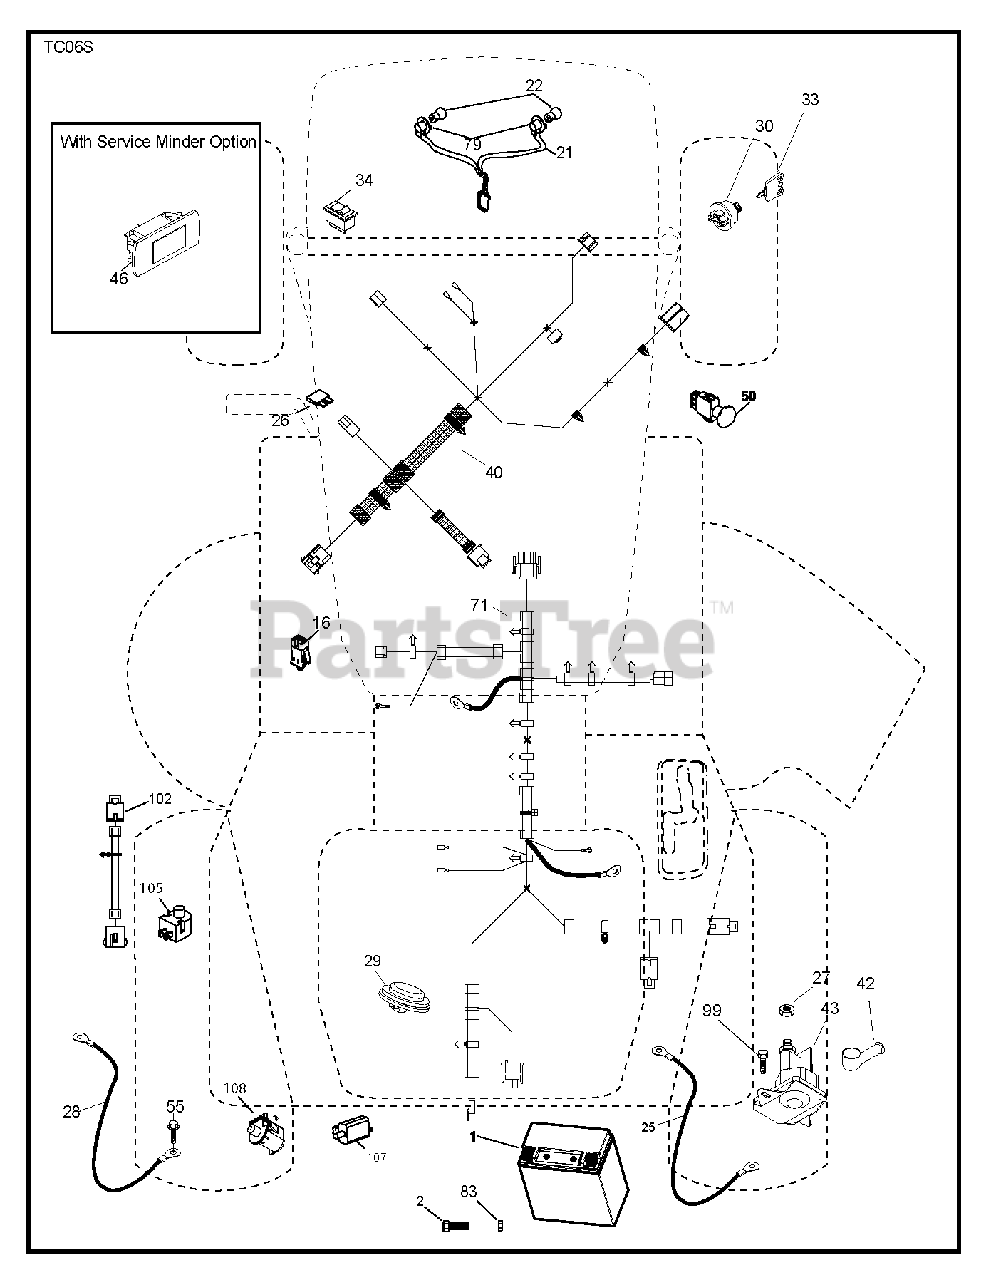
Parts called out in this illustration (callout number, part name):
1	BATTERY BATTERY 14AH 12V LEOC
2	SCREW.HEX.HEAD.CAP.M6 X1.12W
16	SWITCH INTERLOOK PUSH-IN
21	HARNESS.LIGHT W/4152J BULBS
25	CABLE BATTERY CABLE
26	FUSE 20AMP
27	NUT
29	SWITCH.SEAT.DELTA.OPC.
30	SWITCH.IGN.DELTA.W.LGH.ROS
33	KEY.CHAIN.BLISTER.PACK.GEN.INT
40	WIRING HARNESS
42	TERMINAL COVER
43	SOLENOID.W/BRASS.PLUNGER
46	RP GUAGE.SRVCMNDR.HRMTR.
50	RB PTO.SWITCH.8 TERMINAL.BLACK
55	SCREW 5/16"
71	HARNESS
79	BULB HOLDER ASM.
83	NUT NUT SQUARE
99	SCREW
102	HARNESS ASSY
105	REVERSE SWITCH
107	.WITCH.FULL BAGGER.INDICATOR
108	SWITCH.SNAPMOUNT.NC
